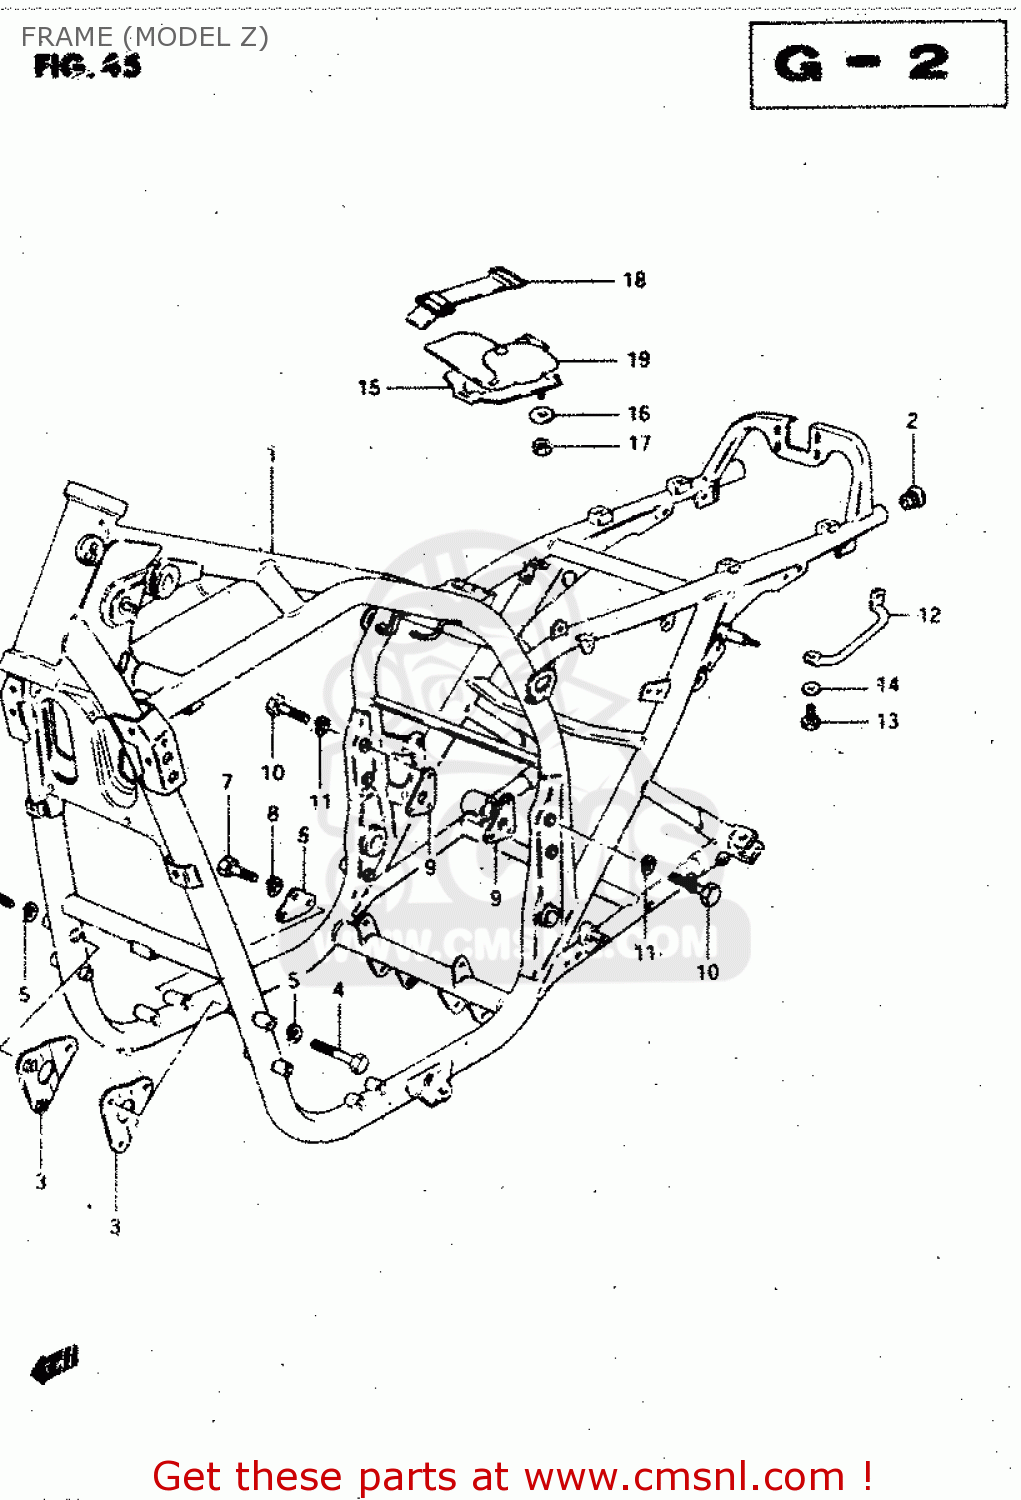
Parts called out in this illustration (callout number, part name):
1	FRAME (SILVER)
2	CAP(OD:26)
3	PLATE,ENGINE MOUNTING
4	BOLT(8X65)
5	LOCK WASHER
6	PLATE,ENG MTG NO.2
7	BOLT 8X16
8	LOCK WASHER
9	PLATE,ENG MTG NO.4
10	BOLT
11	LOCK WASHER
12	GRIP,STAND
13	BOLT
14	WASHER
15	HOLDER,TOOL
16	WASHER(6.5X30X1.6)
17	NUT
18	BAND
19	TOOL SET
